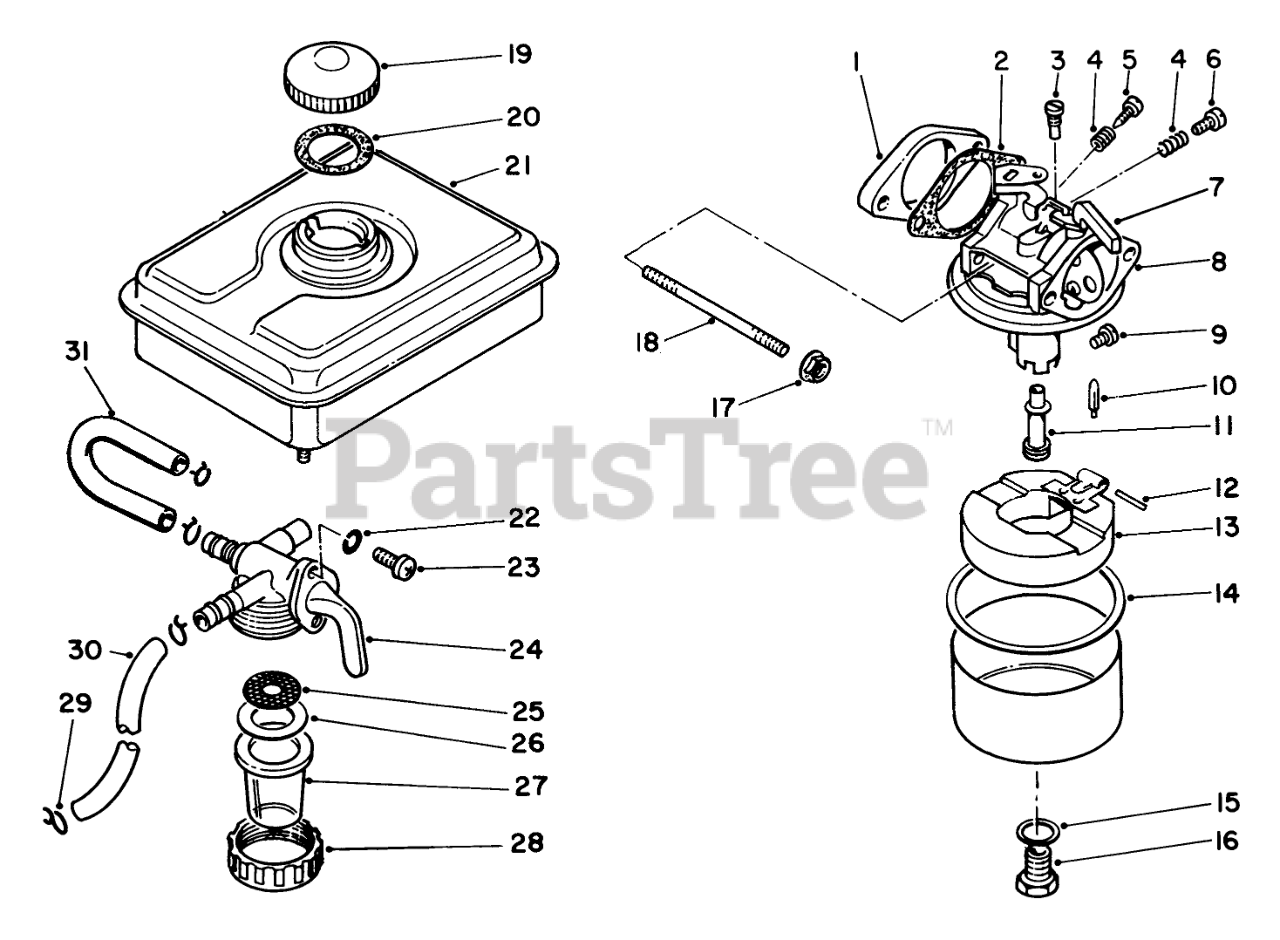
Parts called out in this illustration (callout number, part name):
1	INSULATOR
2	GASKET
3	PILOT JET
4	SPRING
5	ADJUSTER
6	SCREW
7	CHOKE SHAFT ASM
8	Carburetor Assembly (Incl. Ref. #9-16)
9	MAIN JET
10	NEEDLE VALVE
11	NOZZLE
12	Pin
13	FLOAT
14	GASKET
15	GASKET
16	Bolt
18	Stud Bolt
20	GASKET
21	Tank-Fuel
22	Lockwasher
23	Screw
24	Petcock Assembly (Incl. Ref. #25-28)
25	FILTER
26	GASKET
